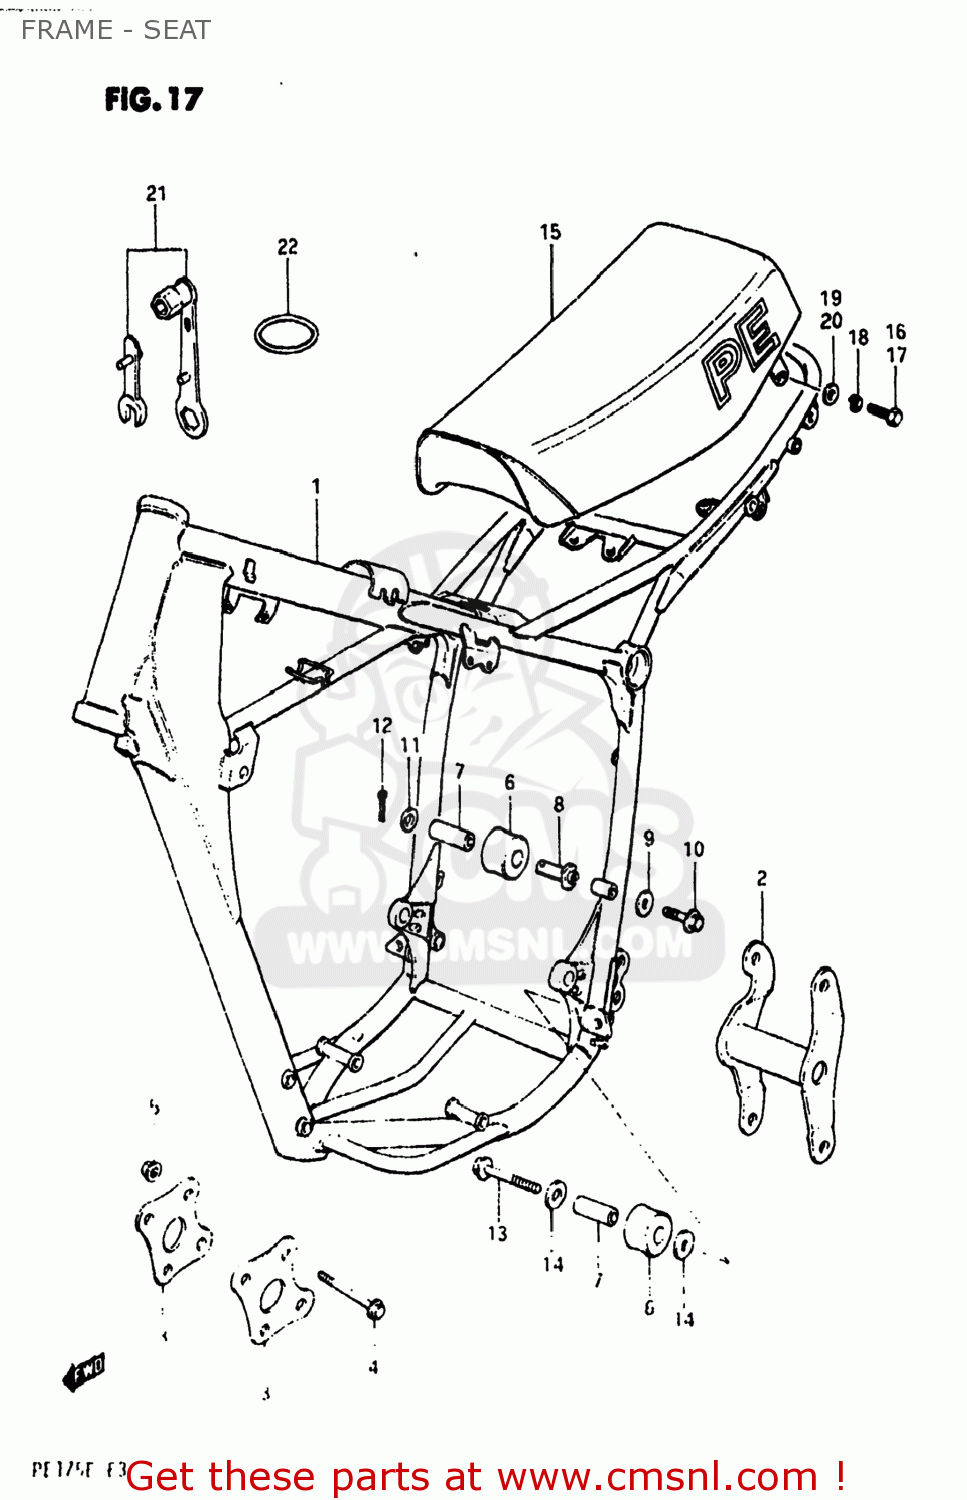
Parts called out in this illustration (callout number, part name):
1	FRAME
2	PLATE,ENGINE MOUNTING
3	PLATE,ENGINE MOUNTING
4	BOLT(8X67)
5	NUT
6	ROLLER,CHAIN LENGTH CONTROL
7	SPACER,CHAIN LENGTH ROLLER
8	BOSS,CHAIN LENGTH ROLL
9	WASHER
10	BOLT
11	WASHER
12	PIN 25X20
13	BOLT(8X41)
14	WASHER
15	SEAT ASSEMBLY
16	BOLT
17	BOLT 8X40
18	LOCK WASHER
19	WASHER (8.5X20X2.6)
20	WASHER (8.7X22X2)
21	SPARK PLUG WRENCH
22	O RING TOOL FITTING
